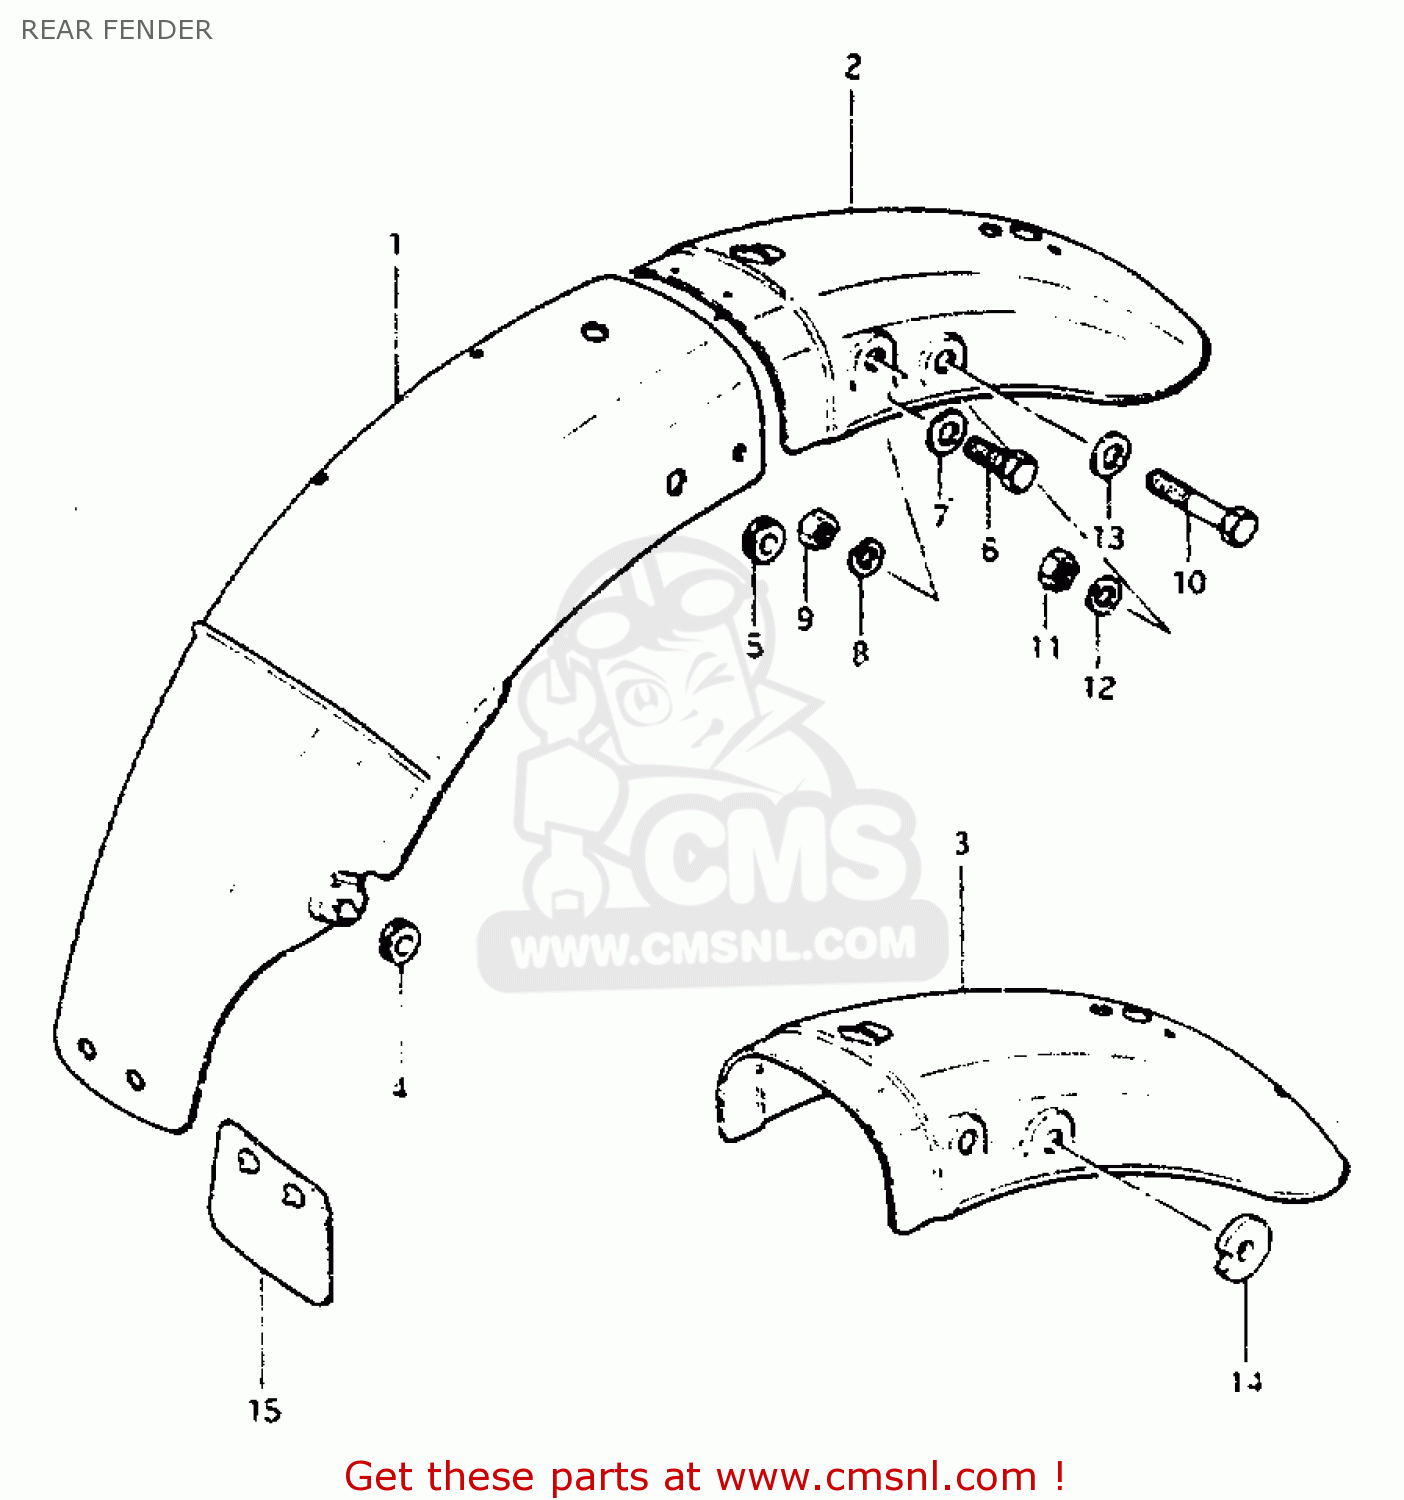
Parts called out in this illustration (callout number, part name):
1	FENDER,REAR
2	FENDER,REAR
4	CUSHION
5	CUSHION
6	BOLT
7	WASHER
8	LOCK WASHER
9	NUT
10	BOLT
11	NUT 8MM
12	LOCK WASHER
13	WASHER
15	GUIDE,RR FENDER MUD
